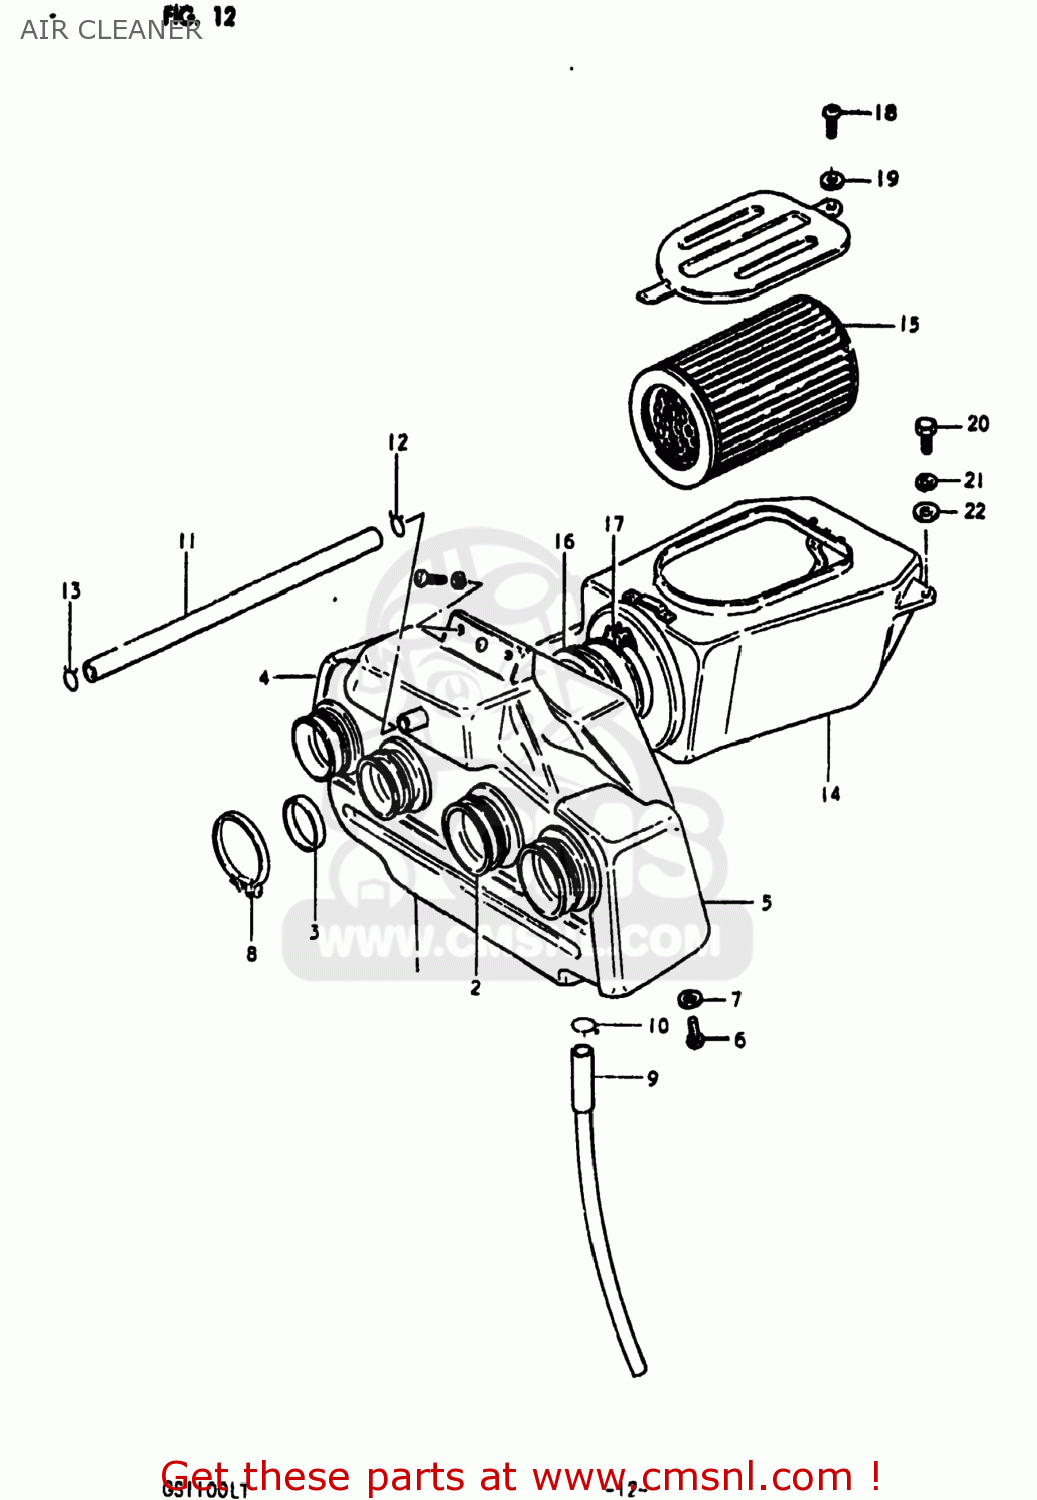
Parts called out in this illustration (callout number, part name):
1	CASE COMP,AIR CLEANER
2	TUBE,AIR CLEANER OUTLET
3	RING,CARBURETOR AIR IN
4	COVER,AIR CLEANER,RIGHT
5	COVER,AIR CLEANER,LEFT
6	SCREW
7	WASHER
8	CLAMP
9	DRAIN TUBE
10	CLIP
11	TUBE,BREATHER
12	CLIP,BREATHER HOSE
13	CLIP
14	CLEANER ASSEMBLY,AIR
15	FILTER,AIR CLEANER
16	JOINT,HOSE AIR CLEANER
17	CLAMP
18	SCREW
19	WASHER
20	BOLT, UPPER
21	LOCK WASHER
22	WASHER
